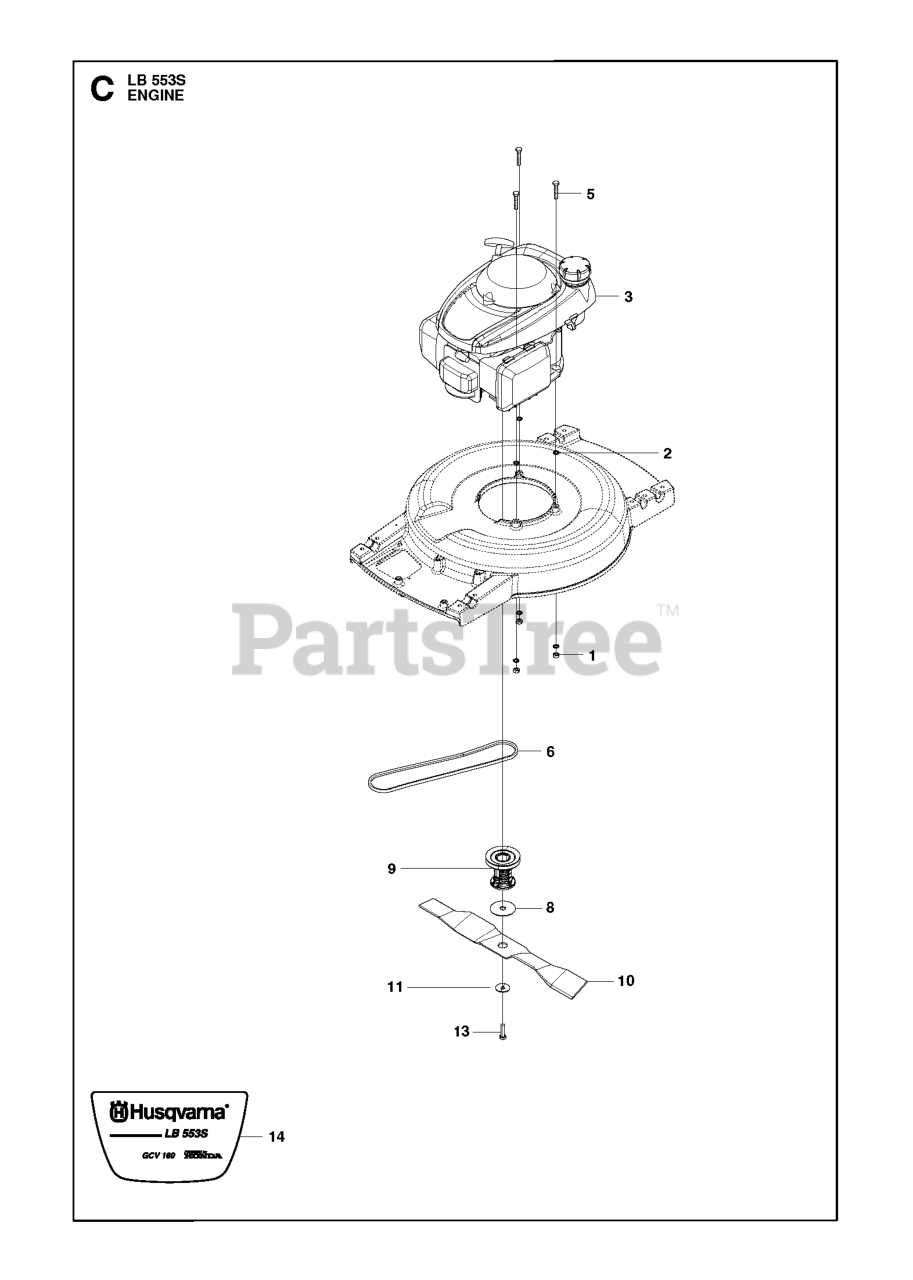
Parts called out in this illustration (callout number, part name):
1	LOCKNUT M8
2	WASHER BRB 8.4X17
6	BELT
8	Washers
